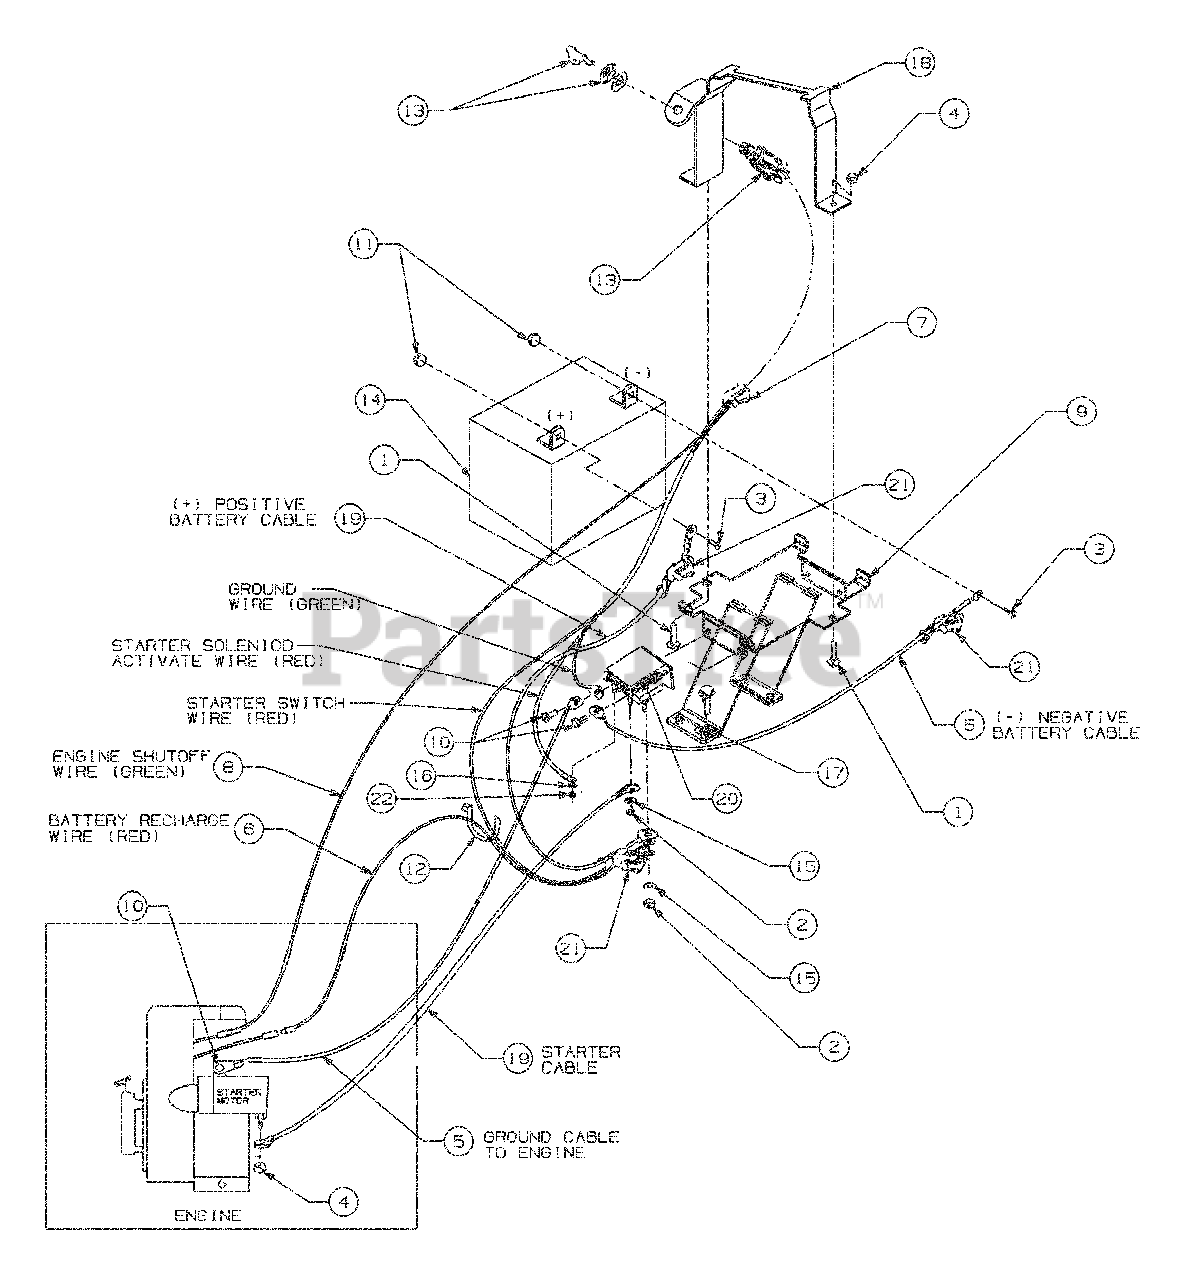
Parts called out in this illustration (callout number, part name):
1	Carriage Screw, 1/4-20 x 1.25
2	Hex Nut, 5/16-24
3	Flange Screw, 1/4-20 x .625
4	Hex Locknut, 1/4-20
5	Cable (ground wire to starter motor bracket)
6	Recharge Wire Assembly
7	Wire Harness Assy. (available as complete assembly only).
8	Ground Wire Assy. (shut off)
11	Hex Nut, 1/4-20
12	Cable Tie
13	Ignition Switch
14	Battery, 270 CCA
15	Lock Washer 5/16
16	Lock Washer, #10
17	External Lock Washer, 5/16
18	Keyswitch Clamp
19	Cable (solenoid to starter motor)
20	Solenoid
21	Boot, Insulating
22	Hex Locknut, #10-32
